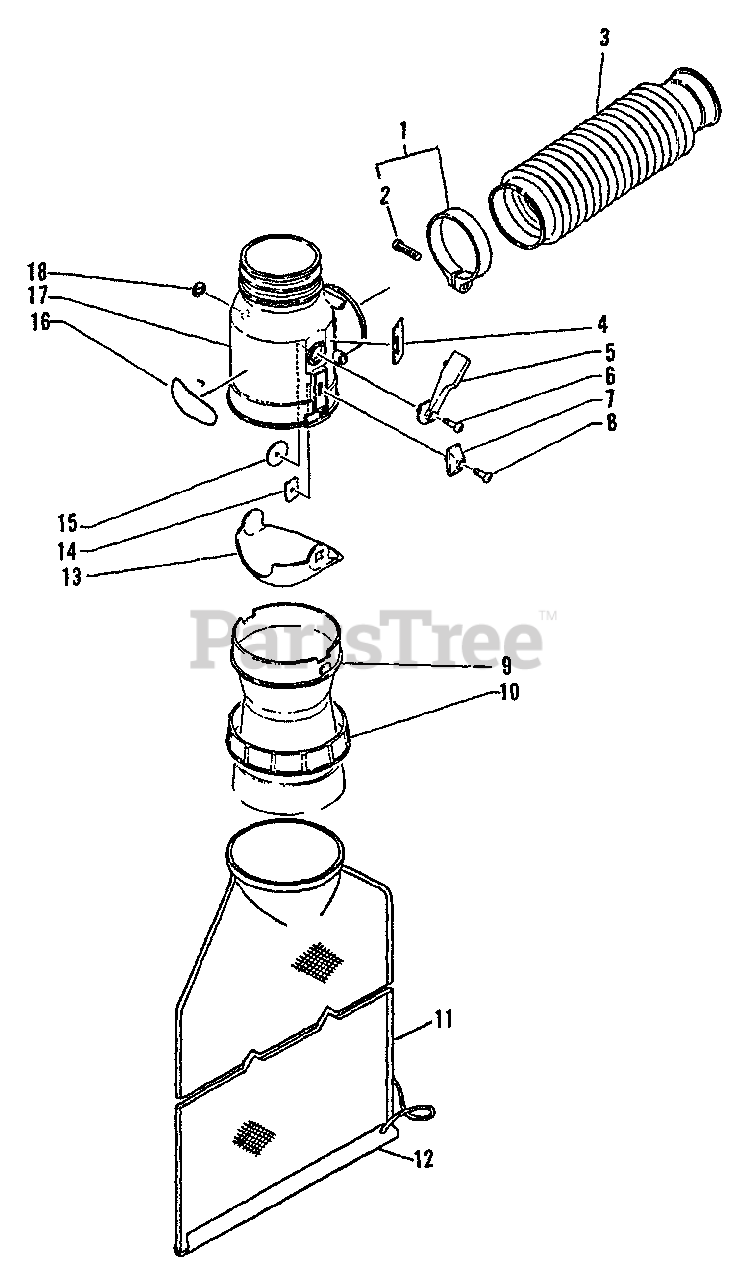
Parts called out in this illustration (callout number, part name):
1	CLAMP KIT
2	SCREW 5×25
3	TUBE, FLEXIBLE
6	SCREW 5×14
8	SCREW 4×14
9	CONNECTOR
11	BAG, VACUUM
12	CLIP, VACUUM BAG
16	LABEL - ECHO
17	TUBE, SUCTION
18	RING, RETAINING - 8
